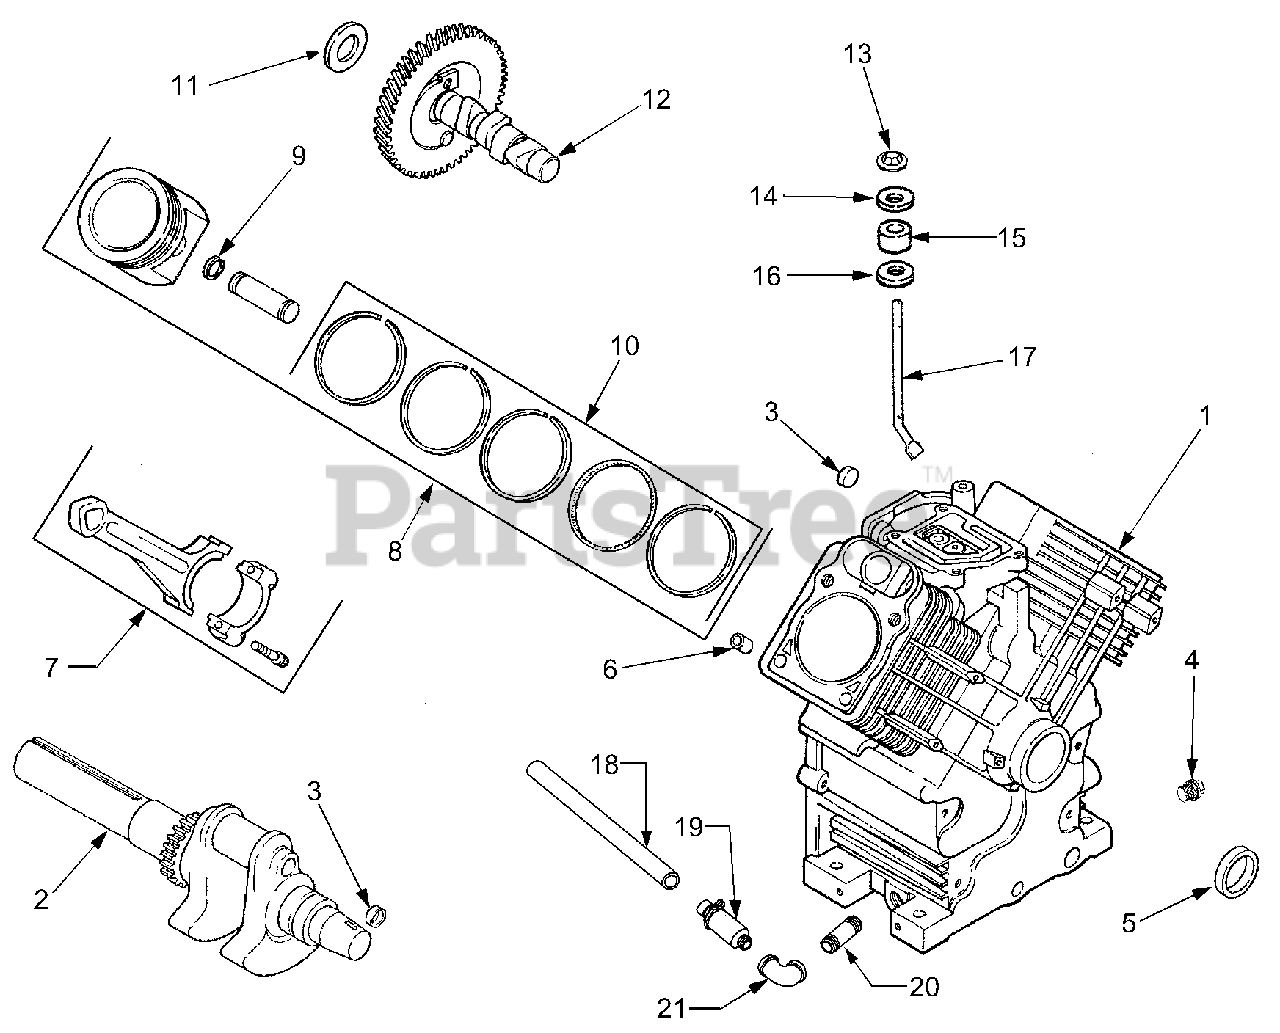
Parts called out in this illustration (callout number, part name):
1	Engine, Complete
2	Crankshaft
3	Plug, Cup
4	Plug, Hex Head, 3/8 NPTF
5	Seal, Oil
6	Pin, Dowel Locating
7	Rod, Connecting, Std
8	Piston w/Ring Set, Std
9	Retainer, Piston Pin
10	Ring Set, Std
11	Shim, Camshaft, .0320
12	Camshaft
13	Ring, Retainer
14	Washer, Nylon
15	Seal, Governor Cross Shaft
16	Washer, Plain
17	Shaft, Governor Cross
18	Hose, Oil Drain
19	Drain, Oil
20	Pipe, Straight
21	Elbow, 90°.
